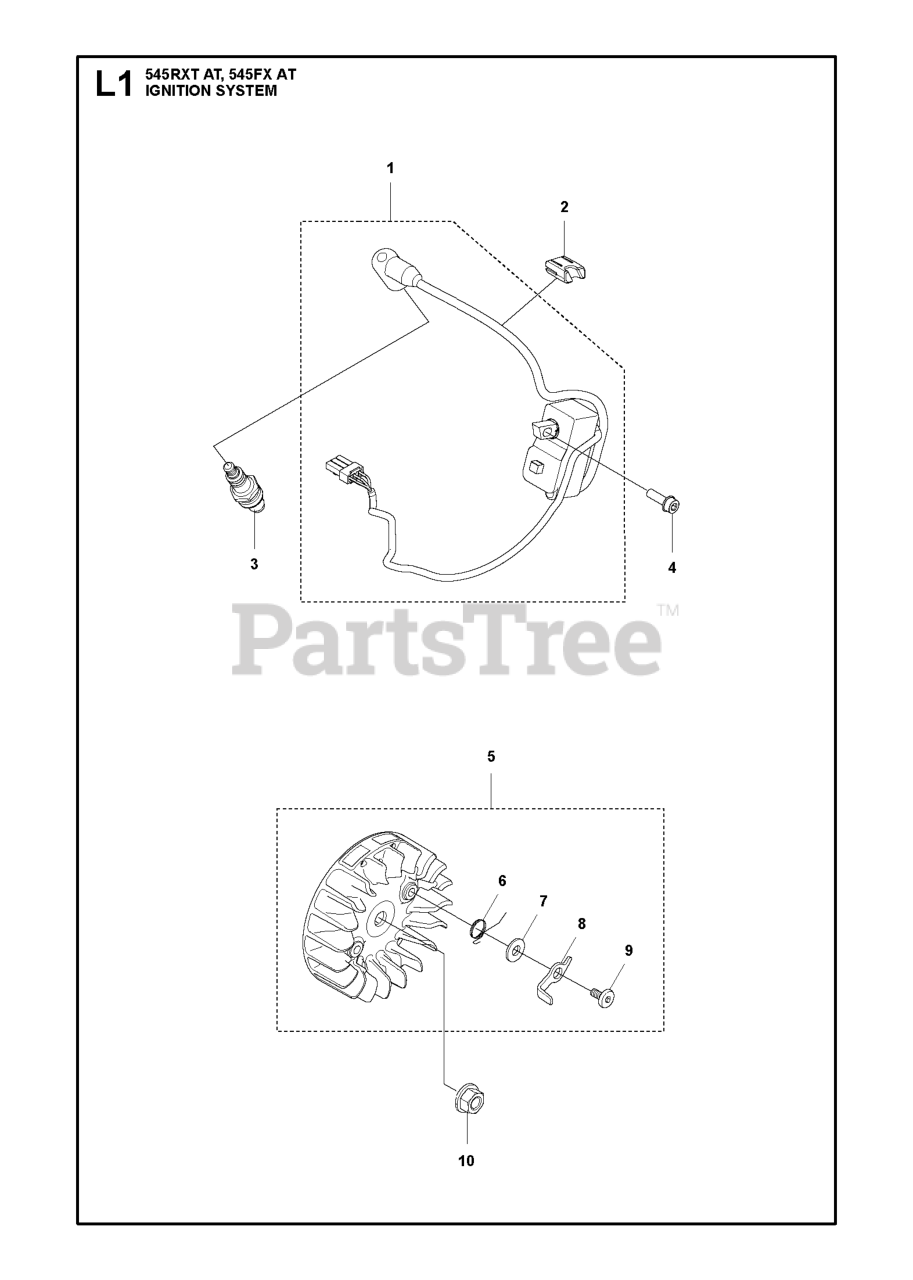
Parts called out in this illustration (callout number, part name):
1	IGNITION MODULE ASSY MBU-67
2	CABLE GUIDE IGNITION CABLE
3	CMR6H SPARK PLUG NGK
4	SCREW IHSCFM
5	FLYWHEEL ASSY D100 SE
6	SPRING PAWL
8	STARTER PAWL
10	NUT W/ WASHER
